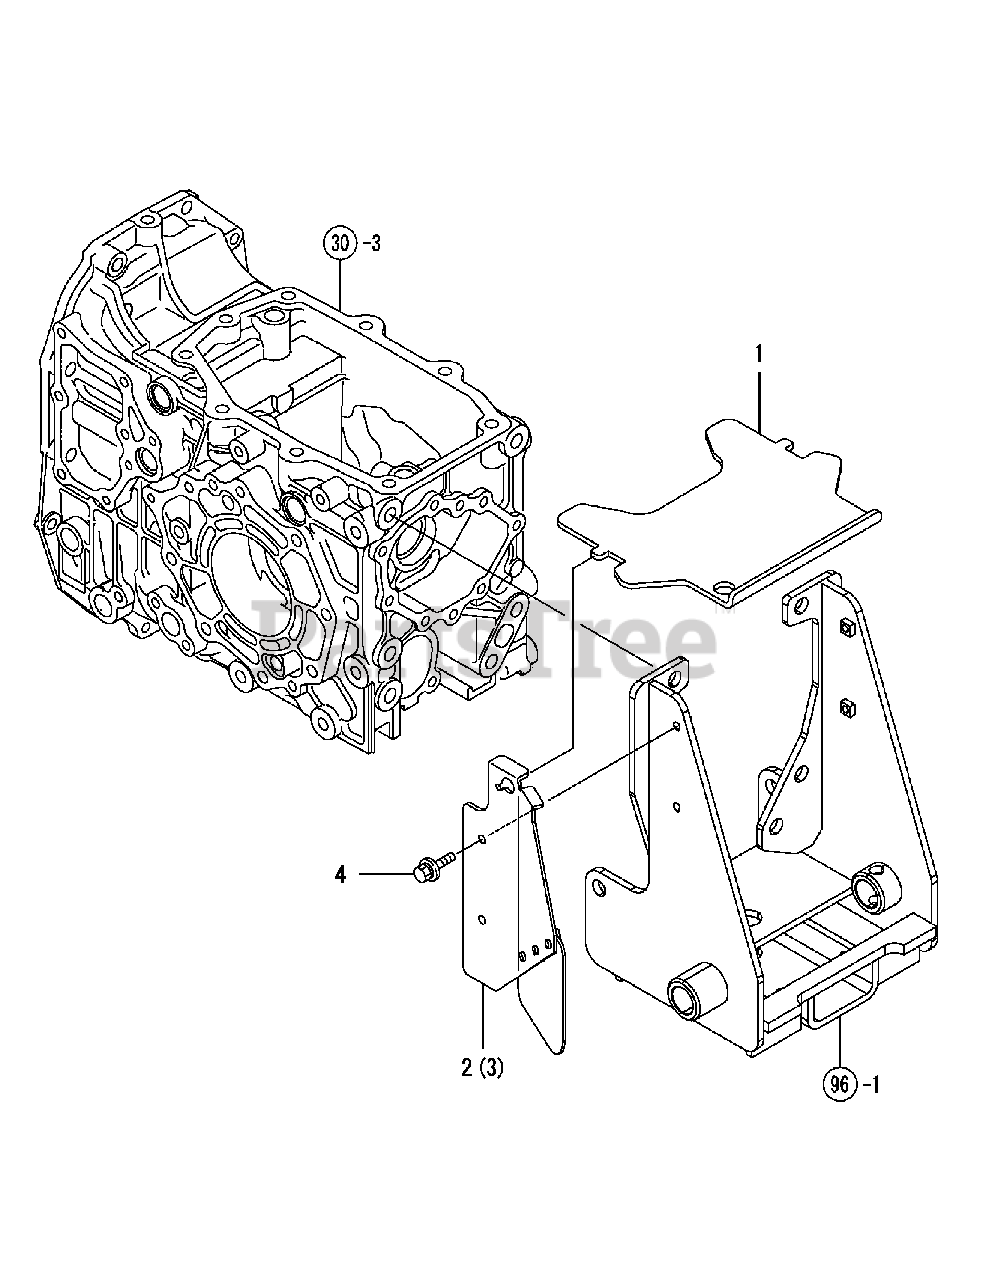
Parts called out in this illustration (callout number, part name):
1	Plate Kit, PTO Guard
2	Cover L, Cmp PTO
3	Cover R, Cmp PTO
